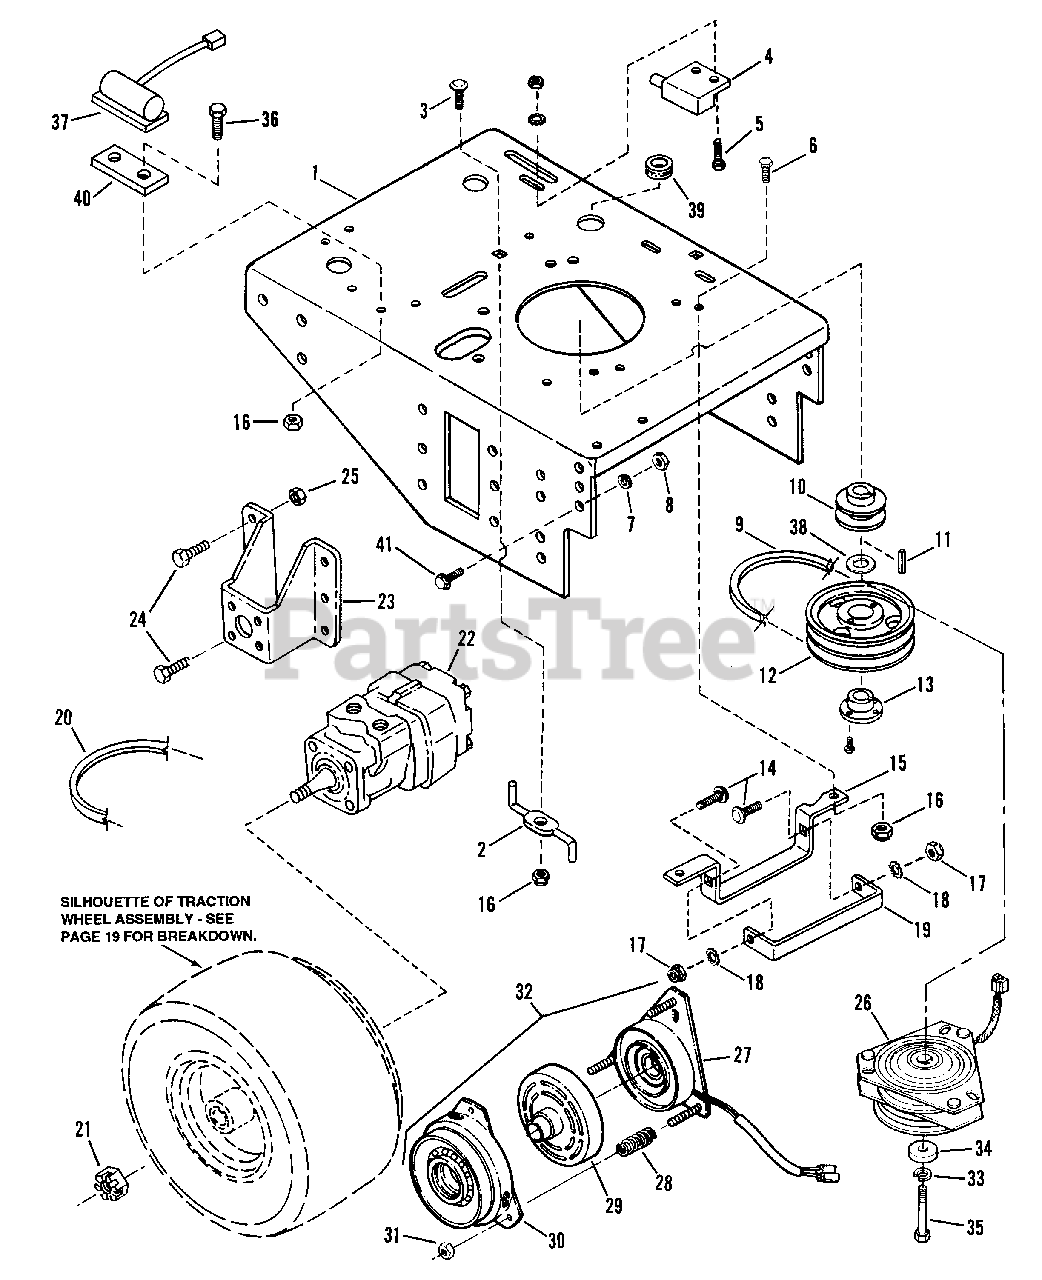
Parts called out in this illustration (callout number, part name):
1	WELDMENT, Rear Deck
2	KEEPER, Belt
3	BOLT, 5/16-18 x 1" Carriage
4	SWITCH, Blade
5	SCREW, #10-24 x 3/4" Slotted Hex Head Flange
6	BOLT, 5/16-28 x 3/4 Hex Head Cap
7	WASHER, 1/2" Split Lock
8	NUT, 1/2-13 Hex
9	BELT, Engine/Deck, 36" Model
10	PULLEY, Engine/Hydro 4"
11	KEY, 1/4" Square
12	PULLEY, Engine/Deck
13	BUSHING, Taperlock
14	BOLT, 1/4-20 x 1" Carriage
15	GUIDE, Engine Belt 36"
16	NUT, 5/16-18 Nyloc
17	NUT, 1/4-20
18	WASHER, 1/4" ITET Lock
19	SUPPORT, Belt
20	BELT, Engine/Hydro
21	NUT, 3/4-28 Pack
22	WHEEL MOTOR
23	WHEEL MOUNT
24	SCREW, 3/8-16 x 1" Hex Head
25	NUT, 3/8-16 Nyloc
26	CLUTCH, Electric
27	COIL, Field
28	SPRING, Coil
29	ROTOR
30	ASSEMBLY, Arm Pulley
31	NUT, 3/8-24 Hex Lock
32	KIT, Electric Clutch
33	WASHER, 7/16 Lock
34	SPACER
35	SCREW, M10- 1.5 x 55mm Hex Head Cap
36	SCREW, 5/16-18 x 1"
37	CAPACITOR
38	BUSHING, 1-1/2" O.D. x 1 I.D.
39	GROMMET
40	MOUNT, Capacitor
41	BOLT, 1/2-13 x 1-1/4" Hex Flange lock
